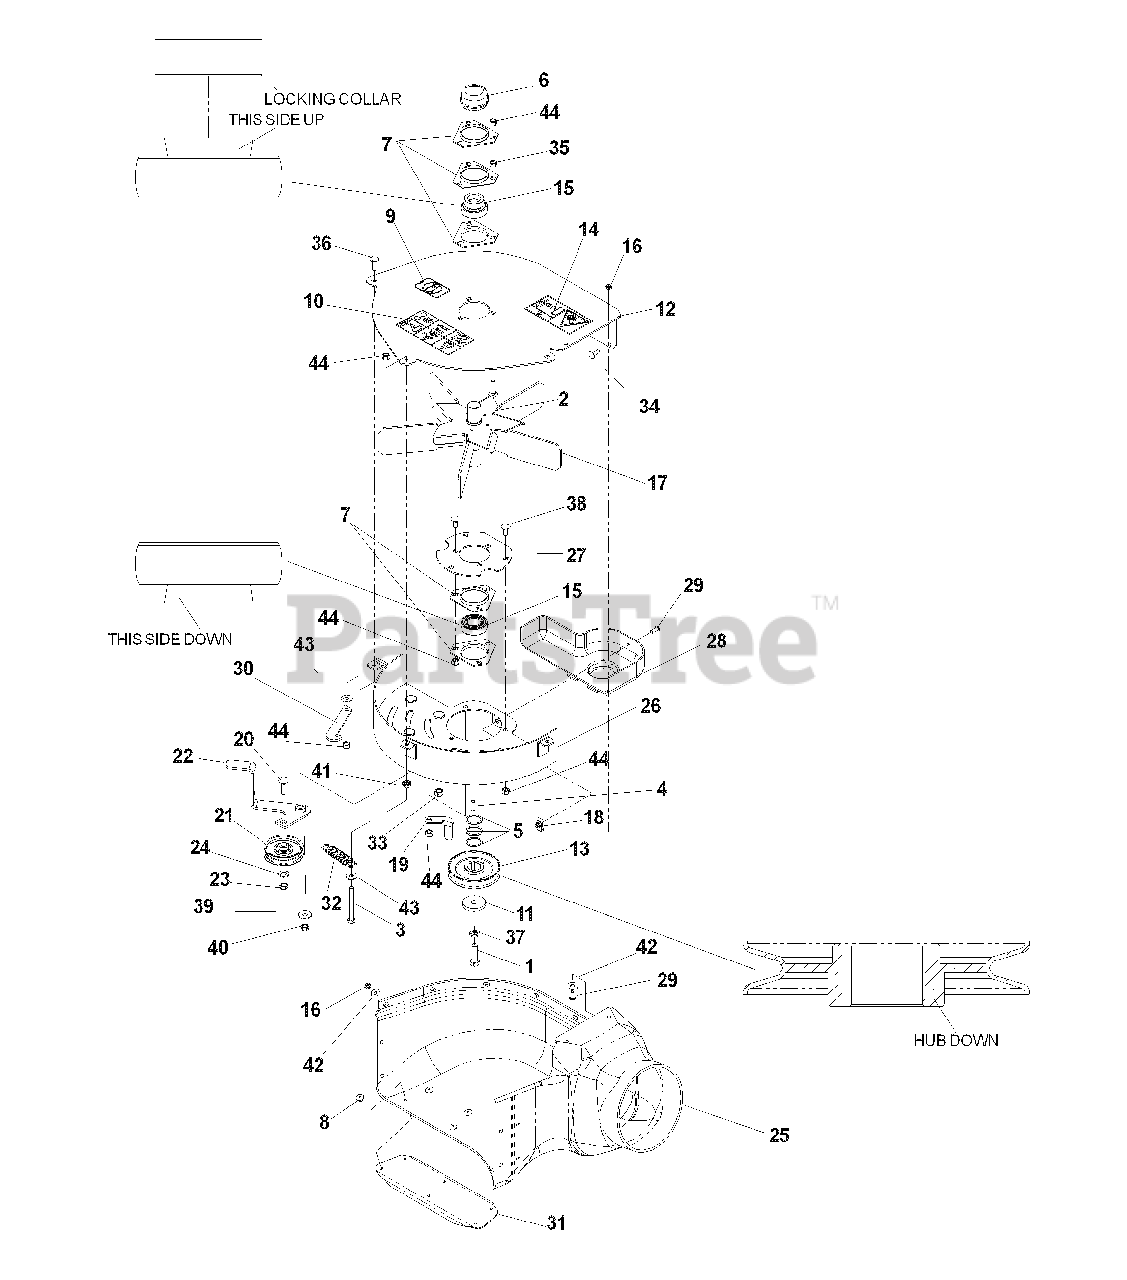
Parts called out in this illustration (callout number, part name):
1	HCS, 7/16-20x1 1/2
2	RHSNB, 5/16-18x1 1/4
3	HCS, 5/16-18x2 3/4
4	KEY,1/4SQx3/4
6	CAP, GREASE
7	BUSHING, FLANGE
8	RIVET,3/16x1/4
9	DECAL, EURO NO STEP
10	DECAL, EURO WARNING
11	WASHER,15/32
12	FAN COVER W/DECALS
14	DECAL, EURO IMPELLER
16	NUT, 1/4-20, THINNYLOC
18	U TYPE RETAINER,1/4C
19	BELT GUIDE
20	RHSNB, 3/8-16x1 1/4
23	NUT, 3/8-16, THIN NYLOC
24	WASHER, 3/8
25	BLOWER HOUSING
26	FLOOR WELDMENT
27	BEARING PLATE
28	PULLEY SHIELD
29	SCREW, 1/4-20x5/8
30	KEEPER, IDLER
31	BLOWER SUPPORT
33	NUT, 3/8-16, NYLOC
34	RHSNB, 1/4-20x3/4, GR2
35	NUT, 5/16-18
36	RHSNB, 5/16-18 x 1
37	LOCK WASHER, 7/16
38	RHSNB, 5/16-18 x 3/4
39	WASHER, 3/8
40	NUT, 3/8-16, CENTERLOCK
41	NUT, 5/16-18, WHIZLK
42	WASHER, 1/4
43	WASHER, 5/16
44	NUT, 5/16-18, NYLOC
